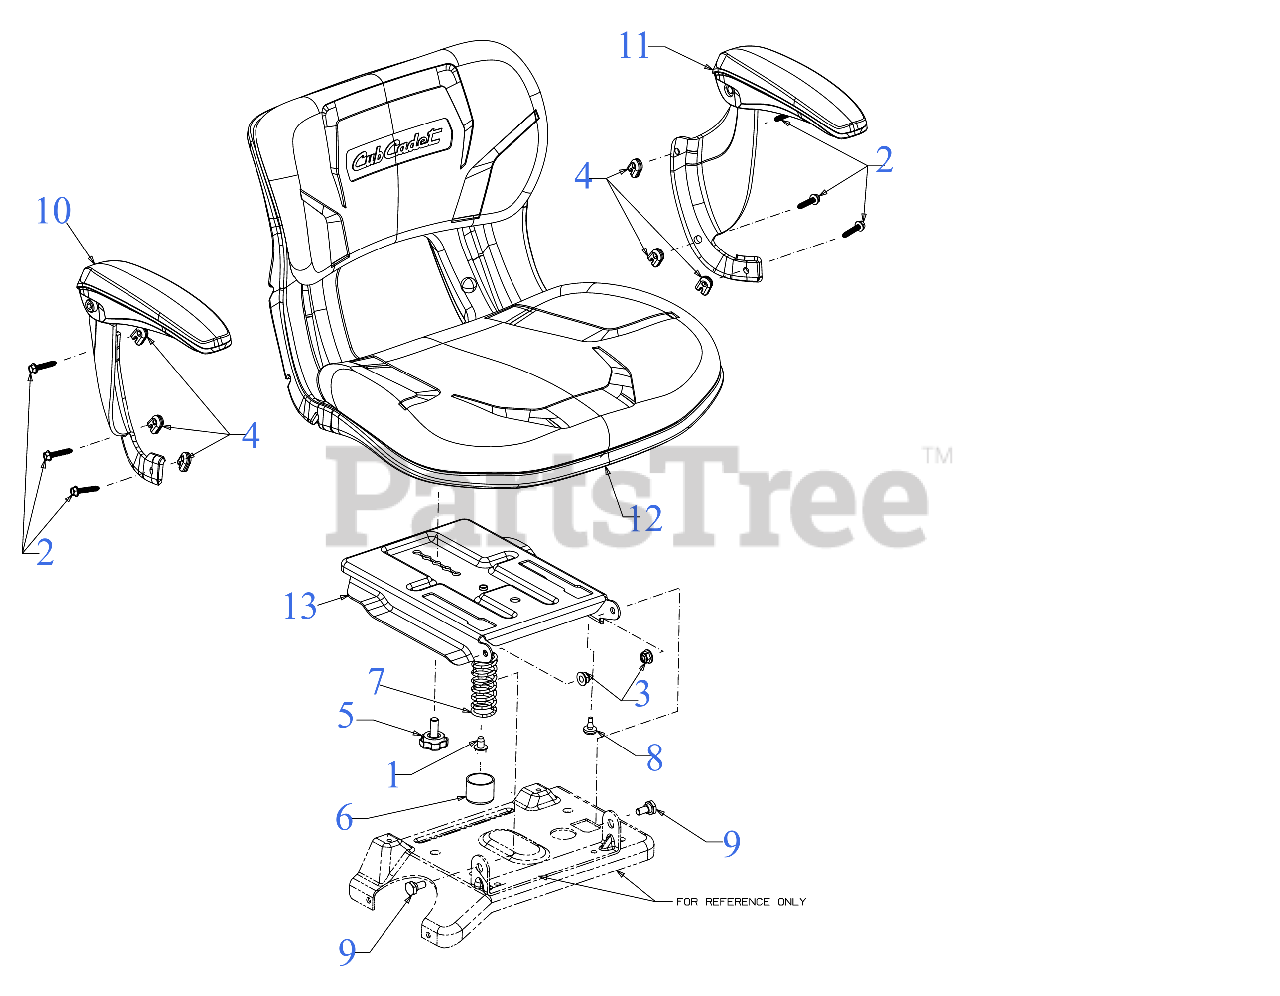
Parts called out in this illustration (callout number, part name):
1	SCREW 5/16-18 x .500
2	SCREW 1/4-14X 1.25
3	FLANGE LOCK NUT 5/16-18
4	ARMREST NUT
5	SEAT ADJUSTMENT KNOB
6	SEAT SPRING CAP
7	SEAT SPRING
8	RUBBER BUMPER
9	SHOULDER SCREW .437 DIA x .180
10	HIGH BACK SEAT ARM (RH)
11	HIGH BACK SEAT ARM (LH)
12	HIGH SEAT (ARM OPT)
